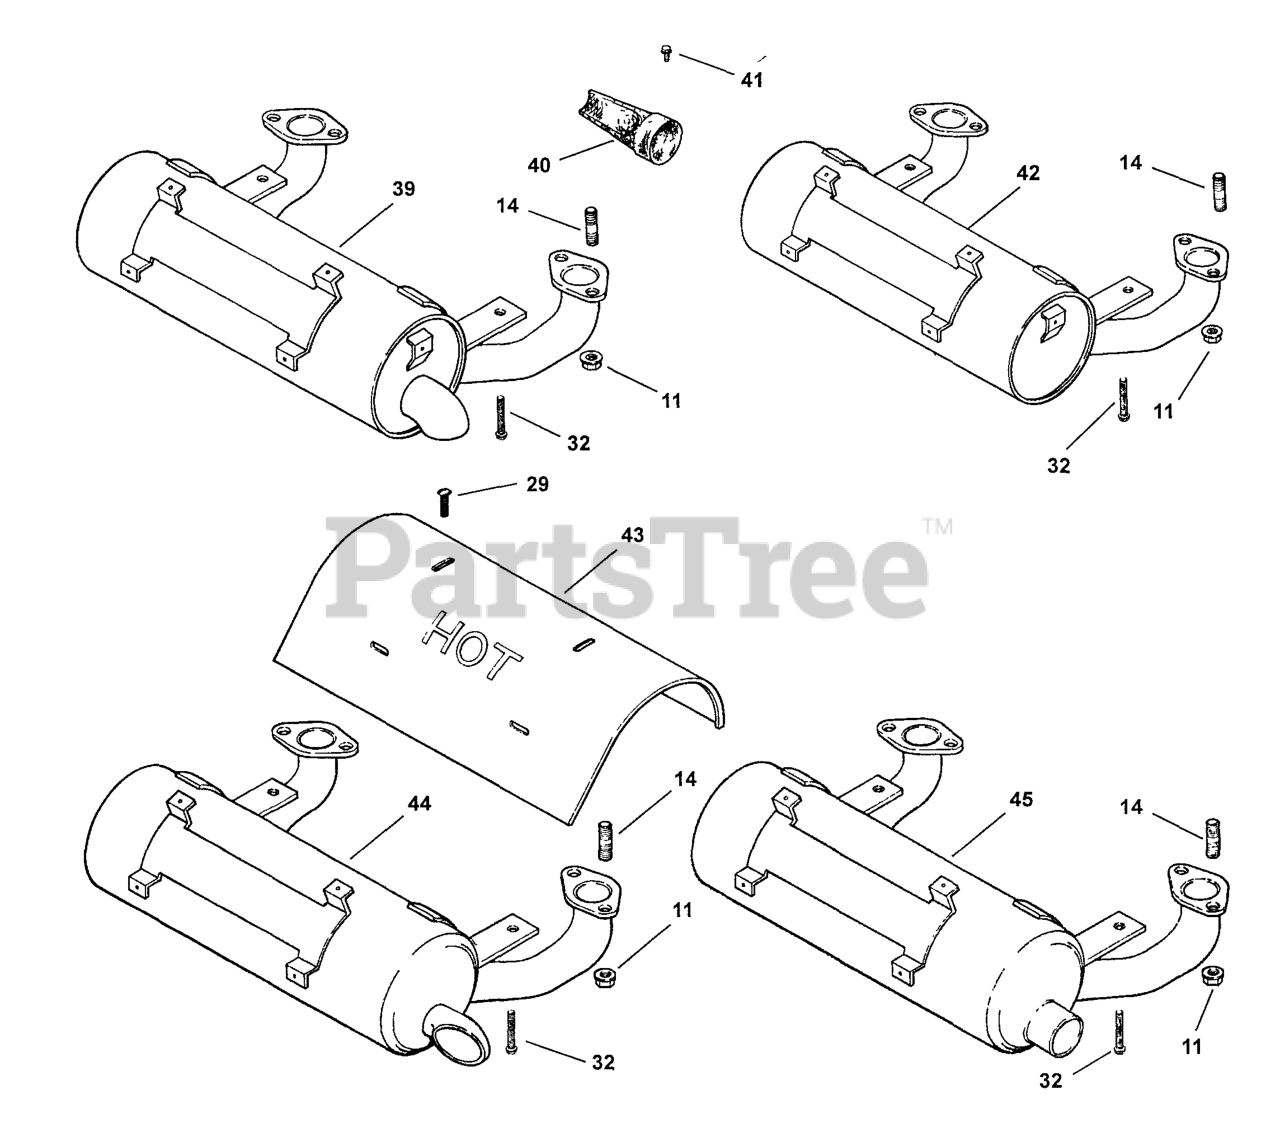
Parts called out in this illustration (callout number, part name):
11	NUT - USE M-841080
14	STUD - USE M-829033
29	SCREW, SEMS DRILL #8-18X1/2"
32	SCREW - USE M-645020
44	MUFFLER - USE 24 068 121-S
